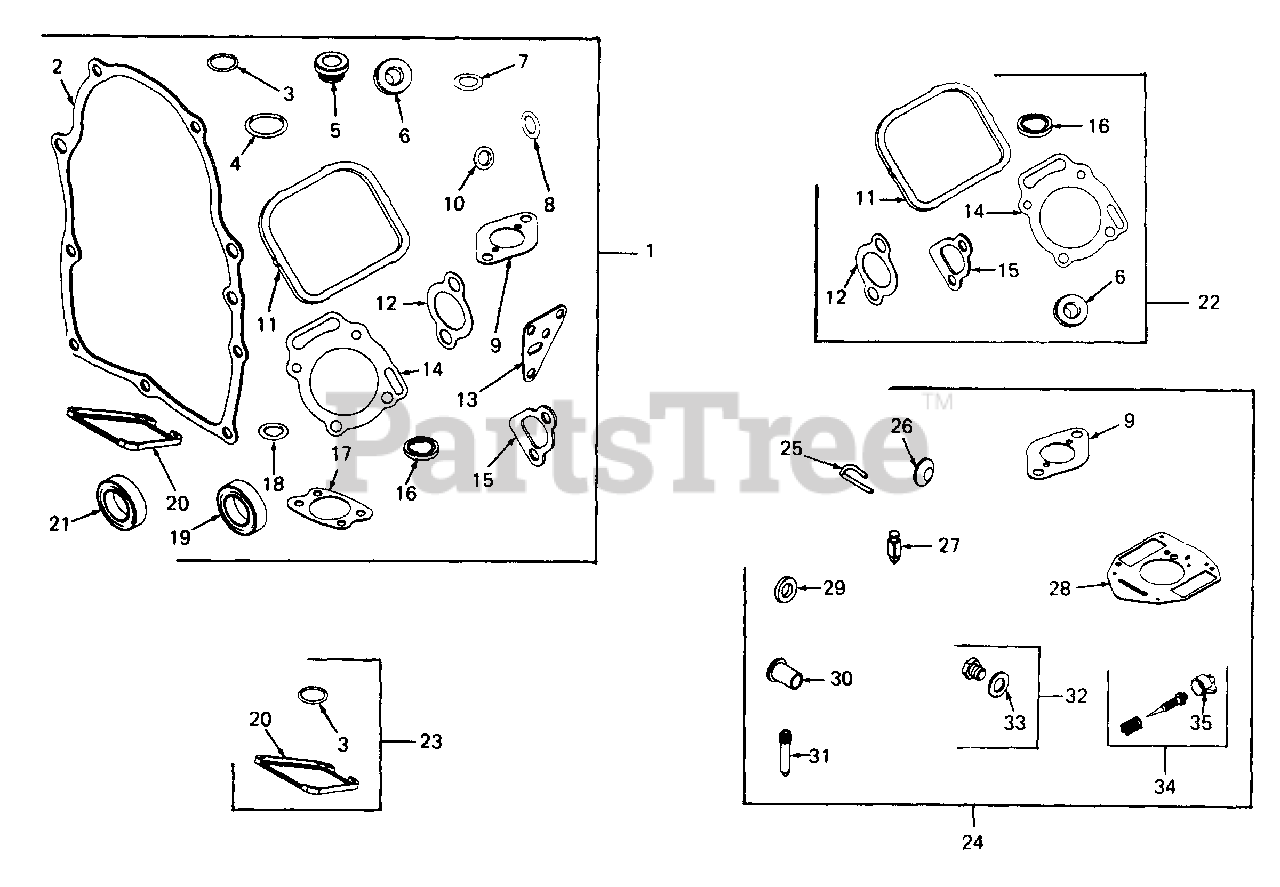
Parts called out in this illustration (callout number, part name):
1	Gasket Set
2	Gasket, Crankcase
3	Seal, Breather Tube
4	Seal, O-Ring
5	Seal, Fill Tube
6	Washer
7	Seal, O-Ring (Crankcase Cover)
8	Seal, O-Ring (Oil Pump)
9	Gasket, Intake
10	Seal, O-Ring (Oil Pump Screen)
11	Gasket, Valve Cover
12	Gasket, Exhaust
13	Gasket, Filter Adapter
14	Gasket, Cylinder Head
15	Gasket, Intake
16	Seal, Fill Plug
17	Gasket, Air Cleaner
18	Seal, Governor Shaft
19	Seal, Oil
20	Gasket, Breather
21	Seal, Oil
22	Gasket Set, Valve
23	Gasket Set, Breather
24	Overhaul Kit, Carburetor
25	Pin, Float Hinge
26	Plug, Welch
27	Valve, Fuel Inlet
28	Gasket, Carburetor Body
29	Collar, Throttle
30	Collar, Choke
31	Nozzle, Carburetor (Slow Speed)
34	Valve, Idle Adjust
35	Cap, Limiter
